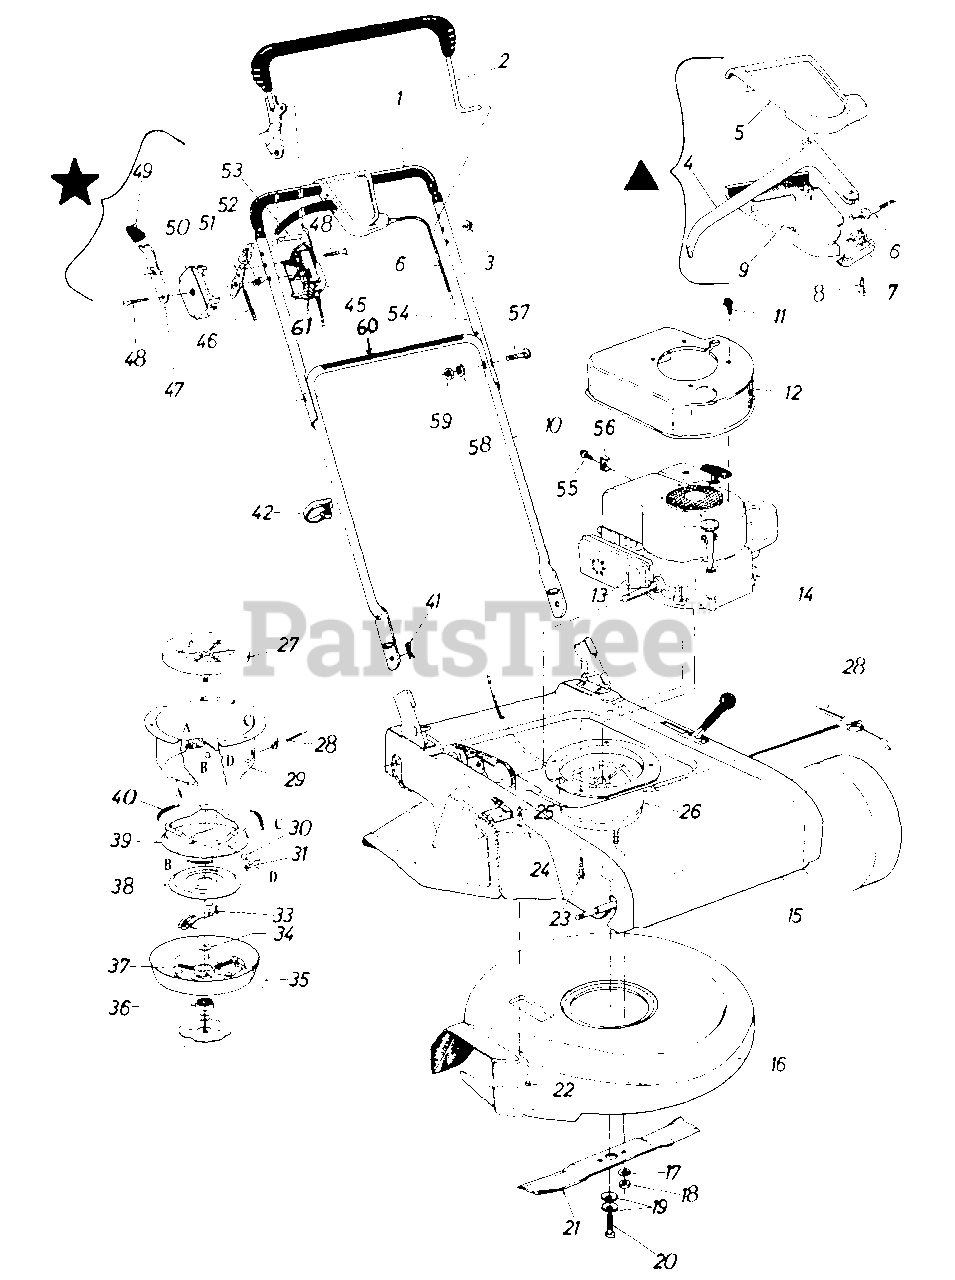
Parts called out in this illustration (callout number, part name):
2	Control Handle - R.H.
3	Cap Speed Nut 5/16 Rod
4	Control Lever
5	Control Cover Half - Upper
6	Drive Clutch Cable - 59"
7	Cable Mounting Cap
8	Flat C'Sunk Hd. Tap Scr. #10 x 1" Lg.
9	Control Cover Half - Lower
10	Lower Handle
11	Hex Wash. Hd. AB-Tap Scr. #8 x .50" Lg.
13	Spring Pin 3/16 Dia. x 1.5" Lg.
14	Engine
15	Upper Deck Ass'y.
16	Lower Deck Ass'y.
17	L-Wash. 3/8" I.D.
18	Hex Nut 3/8-24 Thd. (Grade 8)
19	Belleville Washer
20	Hex Bolt 3/8-24 x 2" Lg. (Grade 8)
21	21" Blade
22	Carr. Bolt 5/16-18 x .62" Lg.
23	Hex Wash. Hd. TT-Tap Scr. 3/8-16 x 1" Lg.
24	L-Wash. 5/16" I.D.
25	Hex Nut 5/16-18 Thd.
26	Blade Brake/Clutch Ass'y. Comp.
27	Fan Adapter
28	Blade Clutch Cable - 46"
29	Clutch Housing
30	Steel Ball 1/2" Dia.
31	Ball Block
33	Hex TT-Tap L-Scr. 1/4-20 x .75" Lg.
34	Fl-Wash. .69" I.D. x 1.06" O.D.
35	Clutch Blade Housing Ass'y.
36	Ball Bearing
37	Compression Spring
38	Clutching Cone
39	Brake Cup Cone
40	Extension Spring
41	Int. Cotter Pin 5/16" Dia.
42	Cable Tie
45	Clutch Panel Half
46	Throttle Wire - 43"
47	Lockout Spring
48	Truss Mach. Tap Scr. #12 x 1.5" Lg.
49	Spring Lever Knob
50	Control Panel Half
51	Throttle Control Lever
52	Control Disc Pin
54	Upper Handle
55	Hex B-Tap Scr. #10 x .38" Lg.
56	Casing Clamp
57	Curved Carriage Bolt 5/16-18 x 1.38" Lg.
58	L-Wash. 5/16" I.D.
59	Hex Nut 5/16-18 Thd.
60	Control Label-Handle
61	Control Label-Throttle
